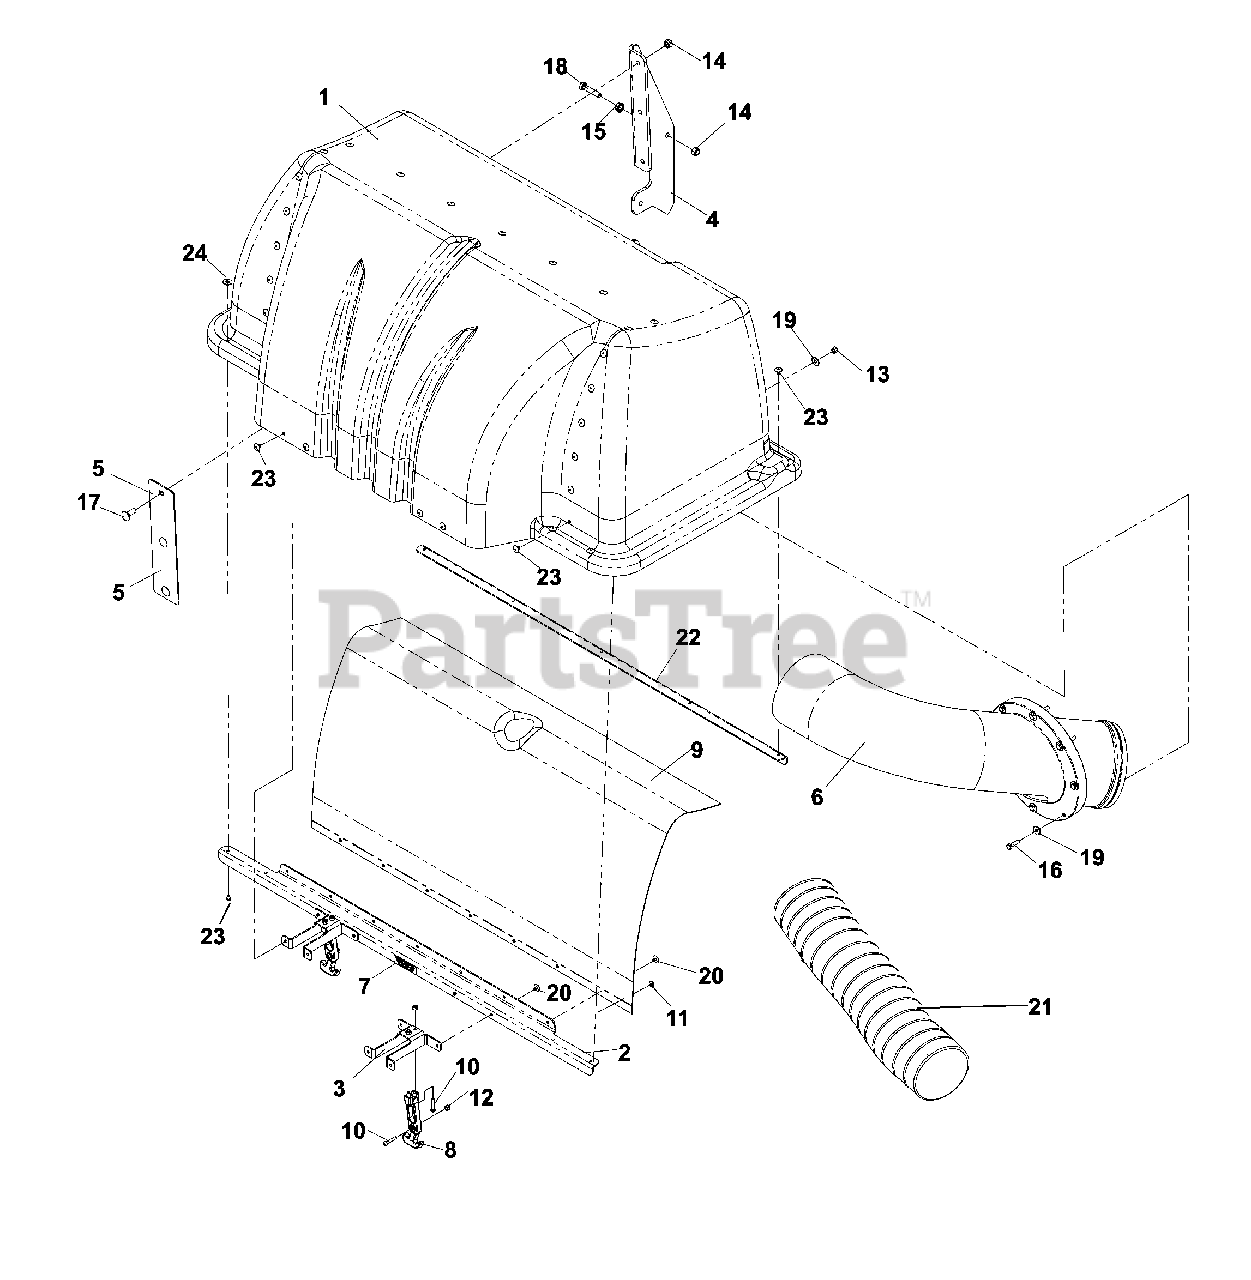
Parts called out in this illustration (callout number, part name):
2	HOOD SUPPORT
3	SUPPORT, DRAW LATCH
4	HOOD HINGE
5	MOUNT PLATE
6	INLET TUB
7	DECAL, VENTILATION
8	DRAW LATCH, FLEXIBLE T-HANDLE
9	MESH, POLY DIAMOND
10	SCR, #10-24 X 1-1/8
11	WASHER #10
12	NUT 10-24 NYLOC
13	NUT 1/4-20 NYLOC
14	NUT 3/8-16 NYLOC
15	NUT 3/8C WHIZ
16	BOLT 1/4C X 1 3/4
17	RHSNB 3/8C X 1
18	HCS 3/8-16 X 1 3/4 GR5
19	WASHER 1/4 FLAT
20	RIVET E/16 X 1/4 LG FLG
21	FLEX HOSE 6 X 60
22	HOOD SUPPORT, REAR
23	RIVERT, 3/16, STAVEX
24	WASHER, #10 MACH SCR BLK OX
